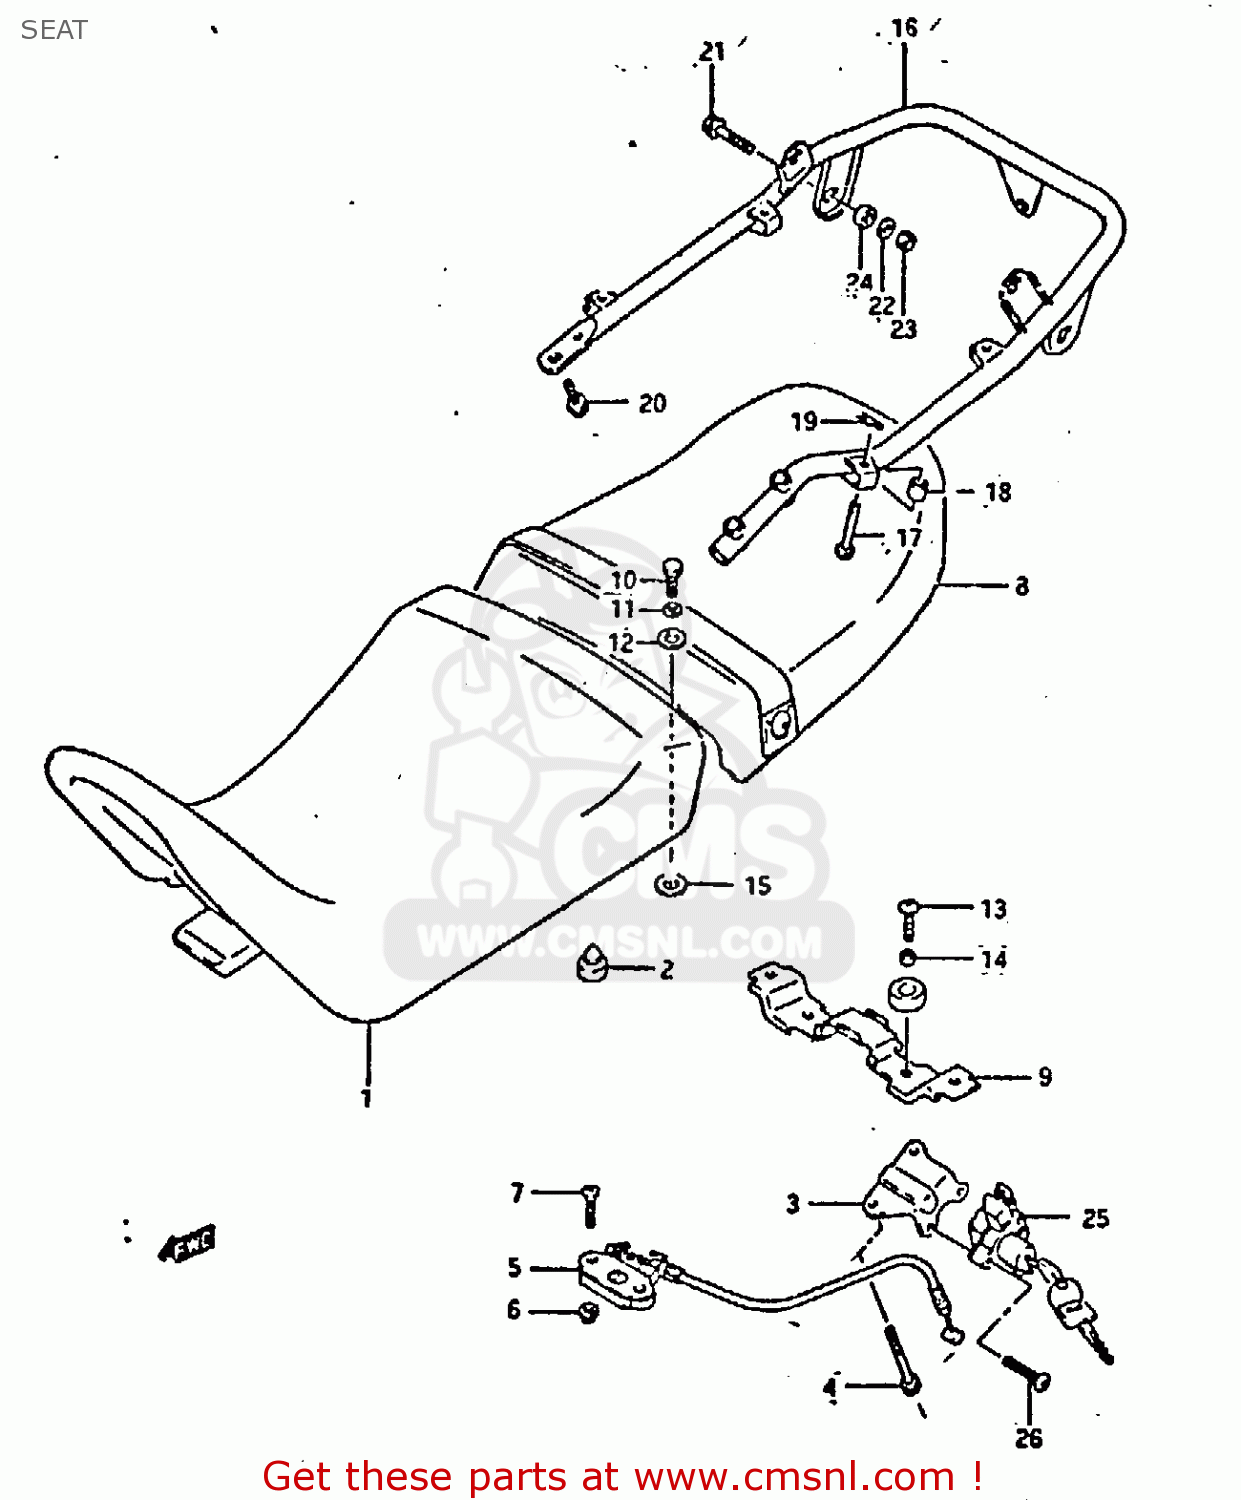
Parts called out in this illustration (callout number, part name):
2	CUSHION,COVER
4	BOLT
6	NUT 6MM
7	SCREW
10	BOLT
11	WASHER,LOCK
12	WASHER(6.5X16X1.2)
13	SCREW
14	SPACER
15	WASHER
18	SPACER,GRIP ROD
19	CLIP
20	BOLT
21	BOLT,FRONT
22	WASHER
23	SPACER(8.2X14X4.5)
24	NUT
25	LOCK SET
26	SCREW(6X20)
